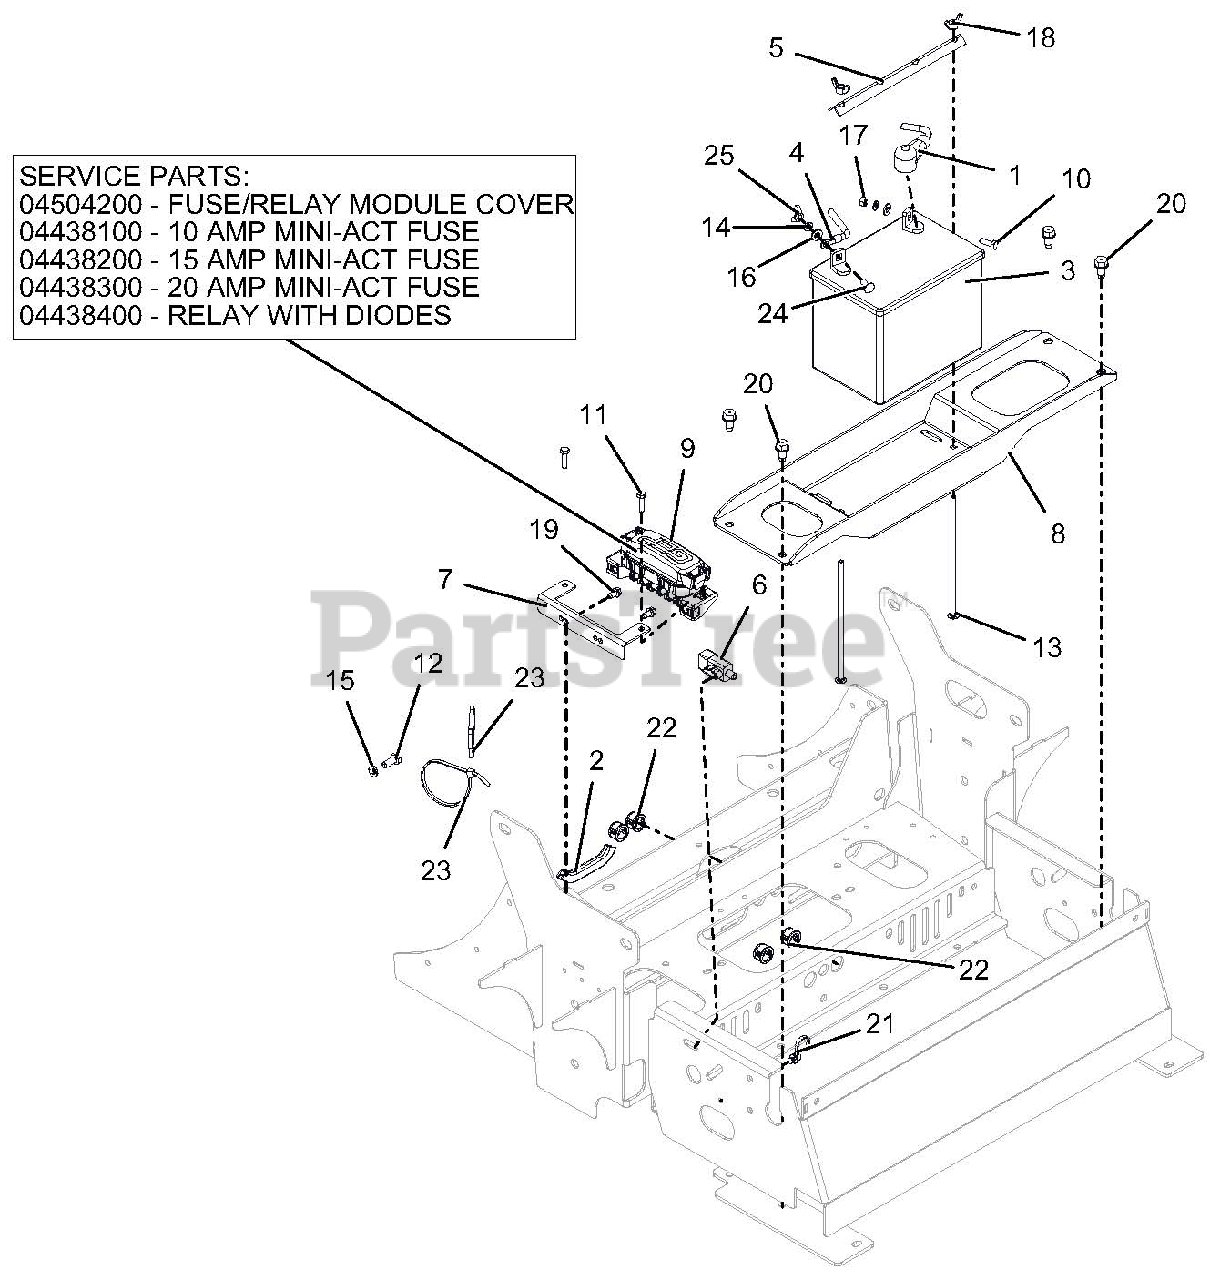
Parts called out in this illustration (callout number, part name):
1	CABLE - POS BATT W/BOOTS 6X35
2	STRIP, COWL
3	BATTERY, 300 CCA 10U1L
4	CABLE-NEGATIVE BATTERY 35.00"
5	HOLD DOWN
6	SWITCH, SNAP IN - N.O./N.O.
7	FUSE HOLDER MOUNTING BRKT -RED
8	PT400 GAS BATTERY TRAY - RED
9	HARNESS, PT400 WIRING
9	COVER, HARNESS FUSE/RELAY MOD
9	FUSE,10 AMP MINI-ATC
9	FUSE,15 AMP MINI-ATC
9	FUSE,20 AMP MINI ATC
9	RELAY,MICRO5 TERML W/RESISTOR
10	@BLT-HEX .25-20X.75 GR5 YWZC
11	@BLT-HEX M6-1.0X25 YWZC
12	@BLT-HEX M8-1.25X20 YWZC
13	BLT-RDHDSQNK .25-20X7.50 GR2YZ
14	@WSHR-LK .25X.062 REG YWZC
15	@WSHR-LK .31X.078 REG YWZC
16	@WSHR-FL-STL.281X.62X.065 YWZC
17	@NUT-HEX .25-20 YWZC
18	NUT-LK WING .250-20 YWZC
19	SCR-TAP .25-20X.50 HWH TR YWZ
20	@SCR-TAP .38-16X.75 HWH TR YWZ
21	CABLE TIE W/ TREE (.25 HOLE)
22	BUSH, PANEL SNAP .687X.875X.56
23	CABLE TIE LG 5-1/2
24	@BLT-RDHDSQNK .25-20X.75 G5YZ
25	NUT-WING .250-20 YWZC
